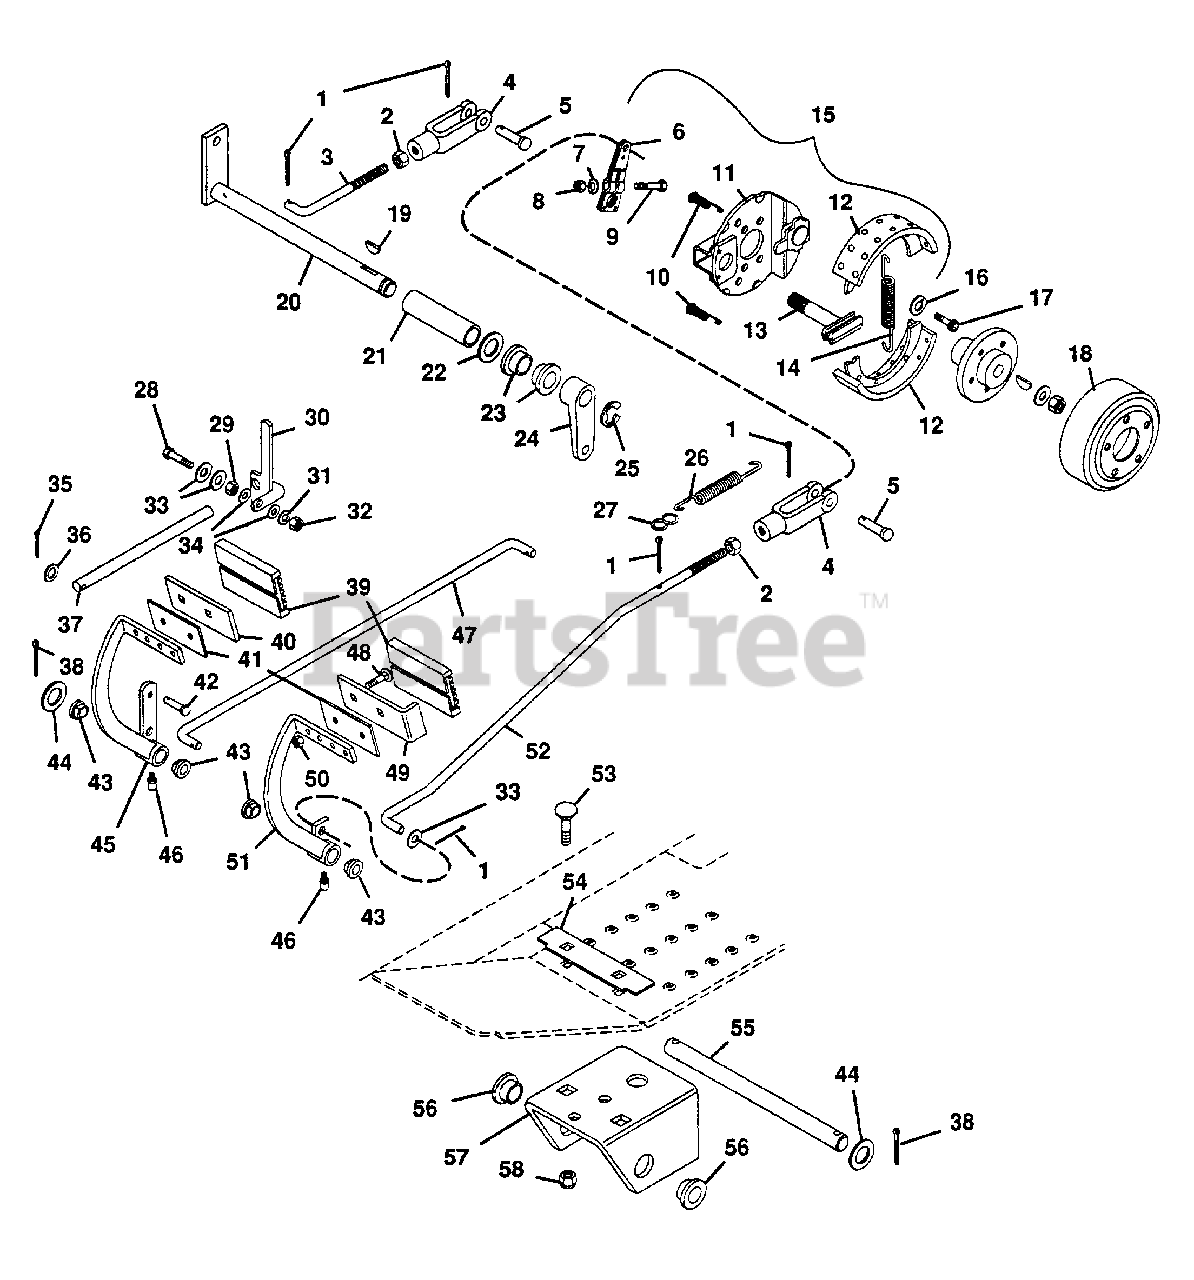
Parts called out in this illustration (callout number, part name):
1	PIN, COTTER .125X.75
2	NUT, JAM 3/8-24
3	ROD, BRAKE CONTROL R.H.
4	CLEVIS, 3/8-24 ADJUSTABLE
5	PIN, CLEVIS .375X.948
6	ARM, CAM LEVER
7	WASHER, LOCK 5/16
8	NUT, HEX 5/16-24
9	BOLT, HEX 5/16-24X1.75
10	SPRING, SHOE RETAINING
11	PLATE, BACK
12	SHOE, BRAKE
13	CAM, BRAKE
14	SPRING, SHOE RETURN
15	BRAKE, 7X1.75 MECHANICAL
16	WASHER, LOCK 1/2 REG.
17	BOLT, 1/2-13X3.50 HEX HEAD CAP
18	DRUM, BRAKE
19	KEY, WOODRUFF .187X.75 HRD #9
20	WELDMENT, BRAKE CROSS SHAFT
21	BUSH., ST. .780X1.00X1.75 STL.
22	WASHER, FLAT .813X1.37X.100
23	BUSH., FLG. .764X1.47X.560 NY.
24	LEVER, PTO
25	E-RING, .750 SHAFT
26	SPRING, EXT. 5.5X.5X20 RATE
27	CLIP, SPRING
28	BOLT, HEX 3/8-16X1.25
29	NUT, JAM 3/8-16 HEX
30	ARM, PARKING BRAKE LOCK
31	WASHER, LOCK 3/8
32	NUT, LOCK 3/8-16
33	WASHER, FLAT .406X.812X.065
34	WASHER, NYLON .375X.75X.06
35	PIN, COTTER .06X.75
36	WASHER, FLAT .281X.625X.065
37	ROD
38	PIN, COTTER .125X1.25
39	PAD, PEDAL
40	PEDAL, BRAKE
41	PLATE, BRAKE
42	PIN, CLEVIS .25X1.03
43	BEARING
44	WASHER, FLAT .656X1.250X.100
45	WELDMENT, BRAKE PEDAL
46	FITTING, LUBE 1/4-28
47	ROD, BRAKE CONTROL L.H.
48	BOLT, CARRIAGE 1/4-20X1.25
49	PEDAL, BRAKE
50	NUT, LOCK 1/4-20
51	WELDMENT, BRAKE PEDAL L.H.
52	ROD, BRAKE CONTROL L.H.
53	BOLT, CARRIAGE 3/8-16X.75
54	STRAP, BRAKE PEDAL STOP
55	SHAFT, BRAKE PEDAL MNTG
56	BUSH., FLG. .630X1.00X.625 NY.
57	BRACKET, BRAKE PEDAL
58	NUT, LOCK 3/8-16
